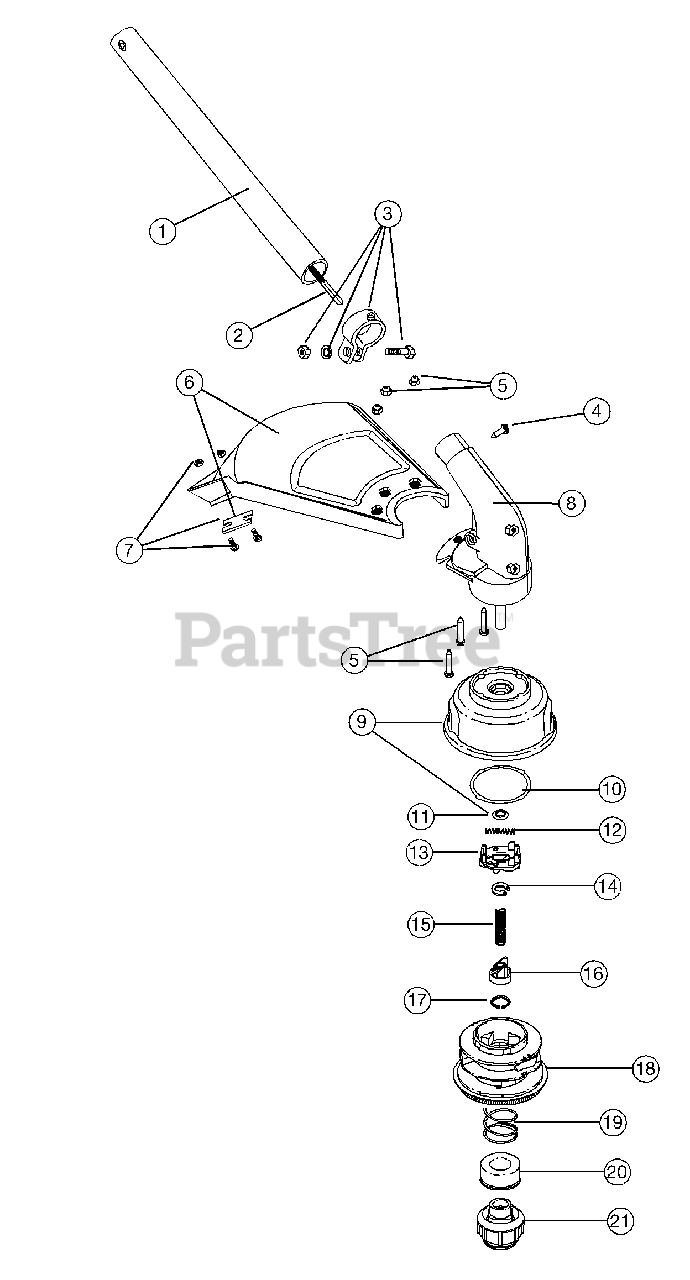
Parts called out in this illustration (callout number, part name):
1	Lower Drive Shaft Housing Assembly
2	Lower Flexible Drive Shaft
3	Lower Clamp Assembly
4	Anti-Rotation Screw
5	Shield Mounting Hardware
6	Shield and Blade Assembly
7	Blade Assembly
8	Gearbox Assembly
9	Outer Spool & Eyelet Assembly
10	Thrust Washer
11	Retaining Ring
12	Small Spring
13	Slider
16	Plunger
18	Inner Reel
19	Large Spring
20	Foam Seal
21	Bump Head Knob Assembly
